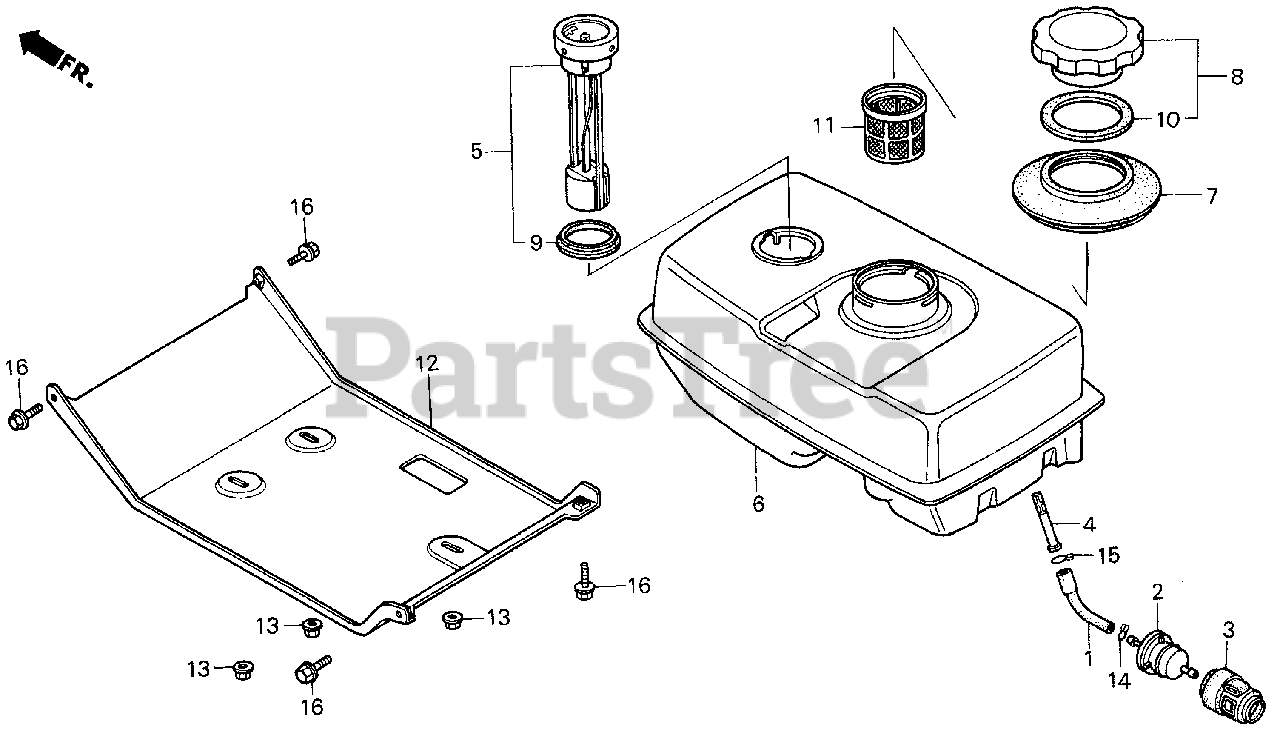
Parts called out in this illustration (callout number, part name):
1	TUBE, FUEL TANK
2	FILTER, FUEL
3	SUSPENSION, STRAINER
4	BUSH, FUEL PURGE
5	METER, FUEL
6	TANK, FUEL
7	SEAL, FUEL FILLER NECK
8	CAP, FUEL TANK
9	GASKET C, FUEL METER
10	GASKET, FUEL FILLER CAP
11	FILTER, FUEL
12	PLATE, FUEL TANK HANGER
13	NUT, FLANGE (6MM)
14	CLIP, TUBE (B8)
15	CLIP, TUBE (B10)
16	BOLT, FLANGE (6X12)
